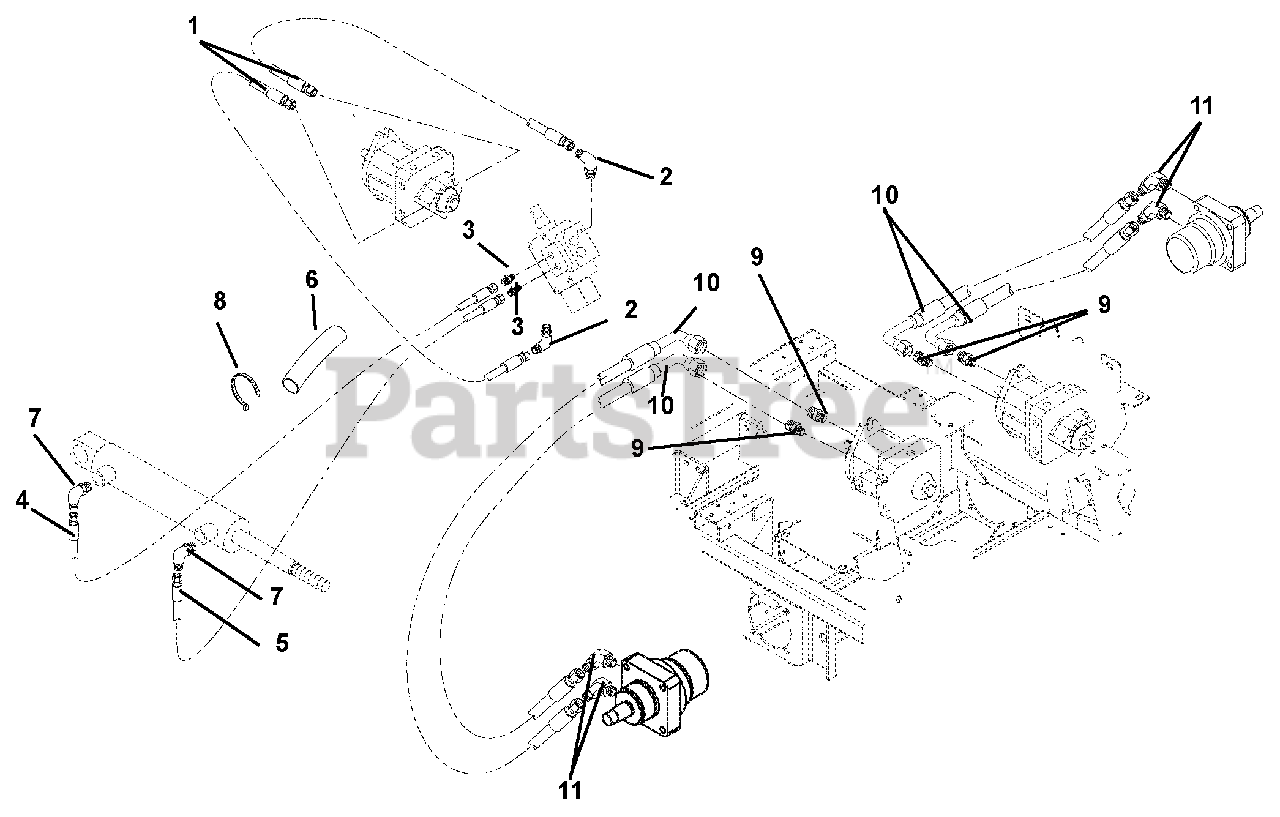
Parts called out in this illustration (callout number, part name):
1	Hose, Hydraulic
2	Hydraulic, Fitting Elbow
4	Hose, Hydraulic
5	Hose, Hydraulic
6	Sleeve Protective 24"
7	Fitting, Hydraulic
8	Cable Tie
9	Adapter, Face Seal 8 x 8 .50 O-Ring
10	Hose, Hydraulic .50
11	Adapter-Hydraulic Steel .875 to .75
